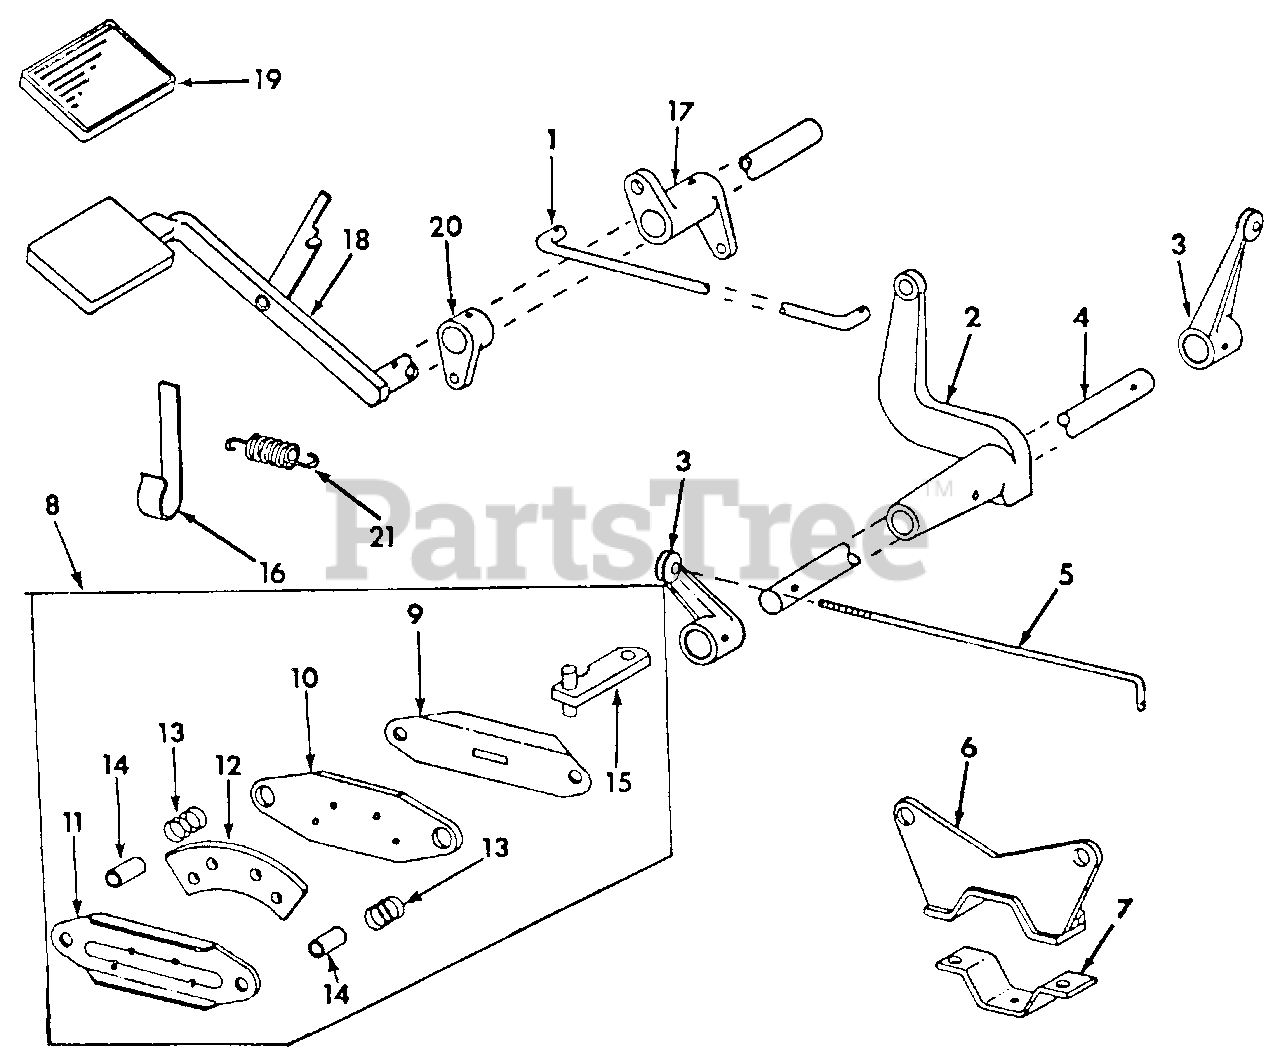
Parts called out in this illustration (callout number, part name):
1	Rod, Brake
2	Lever, Brake
4	Shaft, Brake Pivot
6	Bracket Assy, Caliper
7	Flange, Caliper Mounting
8	Caliper Assy, Brake
9	Plate, Actuator Cam
10	Carrier, Flat Plate
11	Carrier, Rib Plate
12	Liner, Brake
13	Spring, Compression
14	Bushing, Caliper
16	Clip, Safety Switch Release Lever Strip
17	Lever, Brake Rod
18	Pedal Assy, Clutch & Brake
19	Pad, Pedal
20	Lever, Neutral Return
21	Spring, Pedal Return
